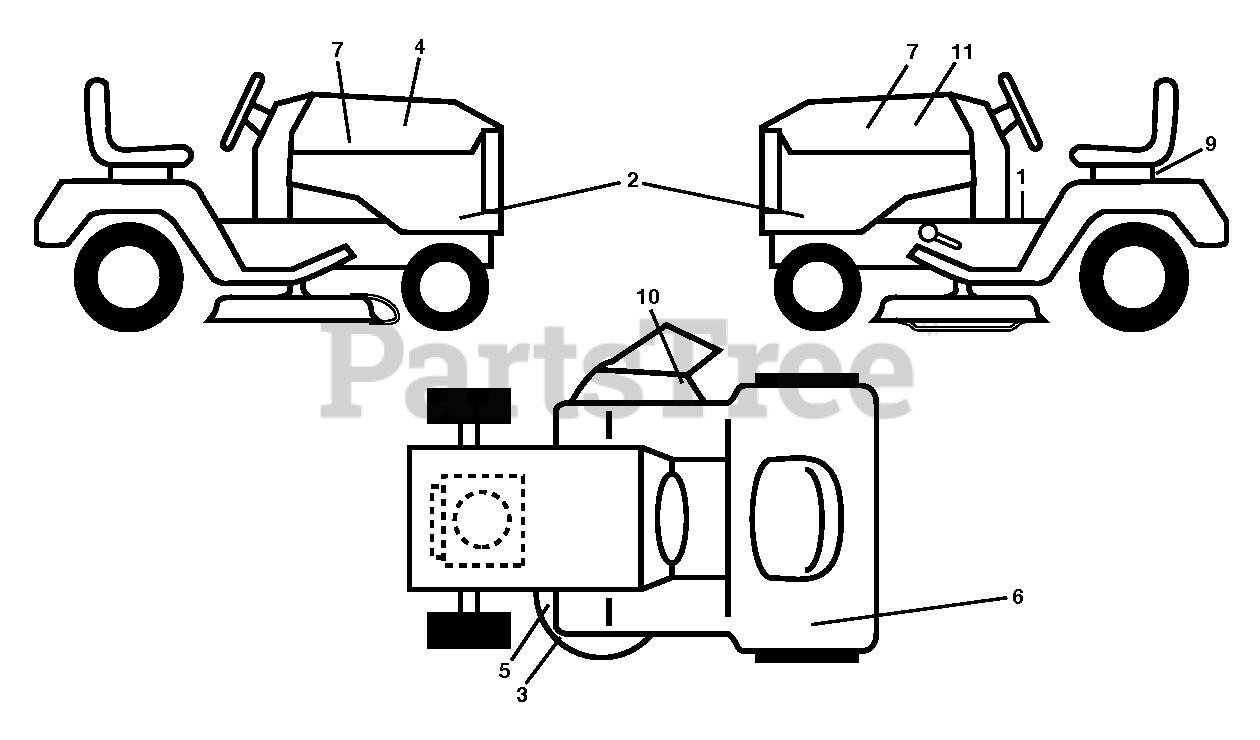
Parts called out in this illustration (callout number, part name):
1	DECAL.FENDER.WARNING.ENGLISH
2	DECAL.SDPNL.HUGT2.GT54CS.SET
3	DECAL.MOWER.CAUTION.TENSION.AR
4	DECAL.WARNING.CUST.RESP.E85.
5	DECAL.MOWER.SCH.48/54.PREM
6	DECAL.RESERVEFUELSELCTR.ENG
7	DECAL.BADGE.170MM.TEXTLOGO.
9	DECAL BTRY SYMBOLS
10	DECAL, DECK DEFLECTOR, WARNING
